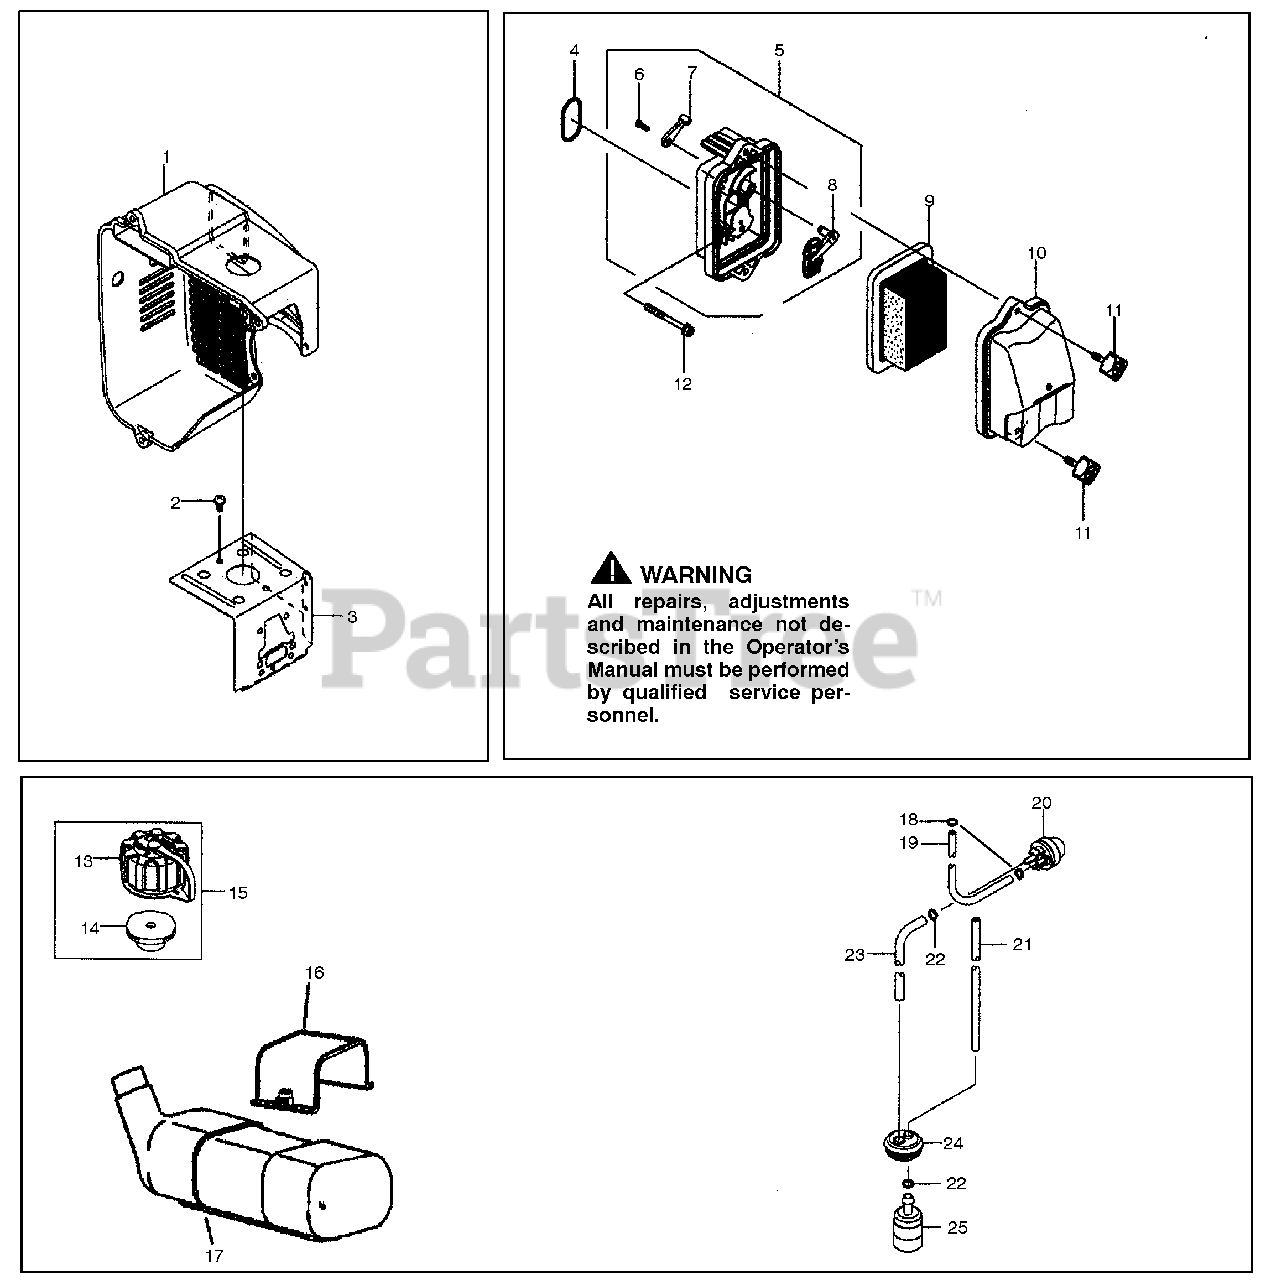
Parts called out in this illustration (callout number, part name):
1	Shround-Engine "A"
2	Screw m5x10
3	Shround-Engine
4	O-Ring 31.2 i.d.
5	Assy-Air filter case
6	Screw m3x10
9	Element-Air Filter
10	Cap-Air Filter
11	Bolt m5x18
12	Screw m5x55
13	Cap-Assy tank
14	Breather
15	Assy-Cap/Breather
17	Fuel Tank
19	Tube 2.3x5x93
20	Pump-Priming carb
21	Tube 3x5x300
23	Tube 3x6x160 "A"
24	Grommet-tank
25	Filter-Fuel
